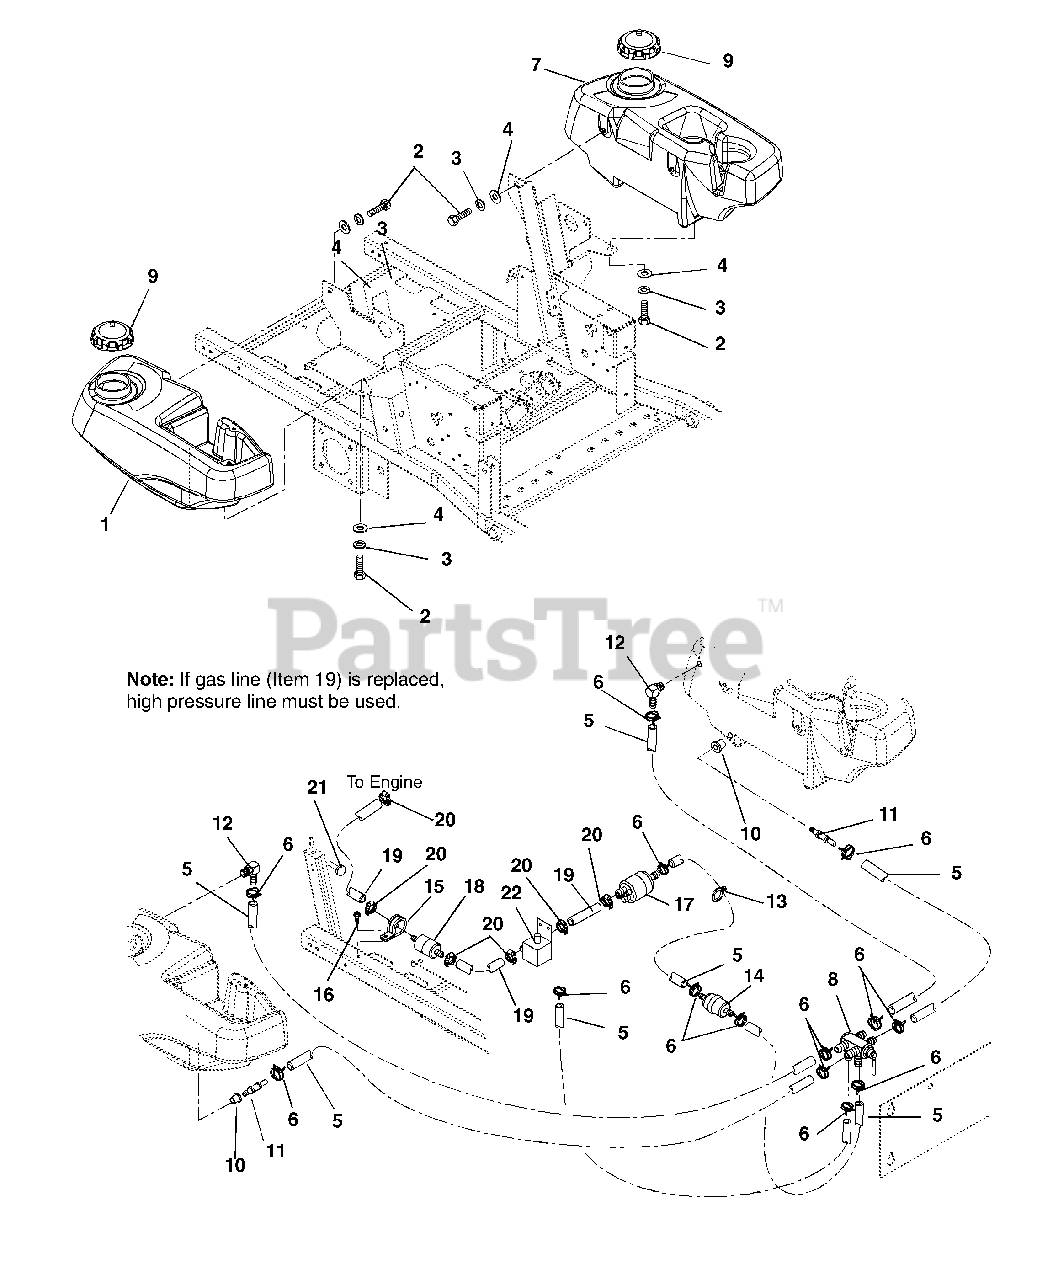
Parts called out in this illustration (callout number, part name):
1	Fuel Tank, Right Hand
2	Bolt-Hex .31-18 x .75 Grade 5
3	Washer-Locking .31 x .078
4	Washer-Flat-Steel .38 x .875 x .083
5	Hose, .31 ID
6	Hose-Clamp
7	Fuel Tank Left-Hand
8	Valve, Fuel
9	Cap-Gas
11	Fitting, Tank with Screen
12	Fitting, Tank
13	Tube Clip 1.50
14	Filter, Fuel .31
15	Clamp, 2.18
16	Screw-Tapping .38-16 x .75 Hex Washer Head
17	Pump, EFI Fuel
18	Filter, Fuel
19	Gas Line .31 ID High Pressure
20	Hose Clamp
21	Tube Clip .75
22	Regulator, EFI Fuel
